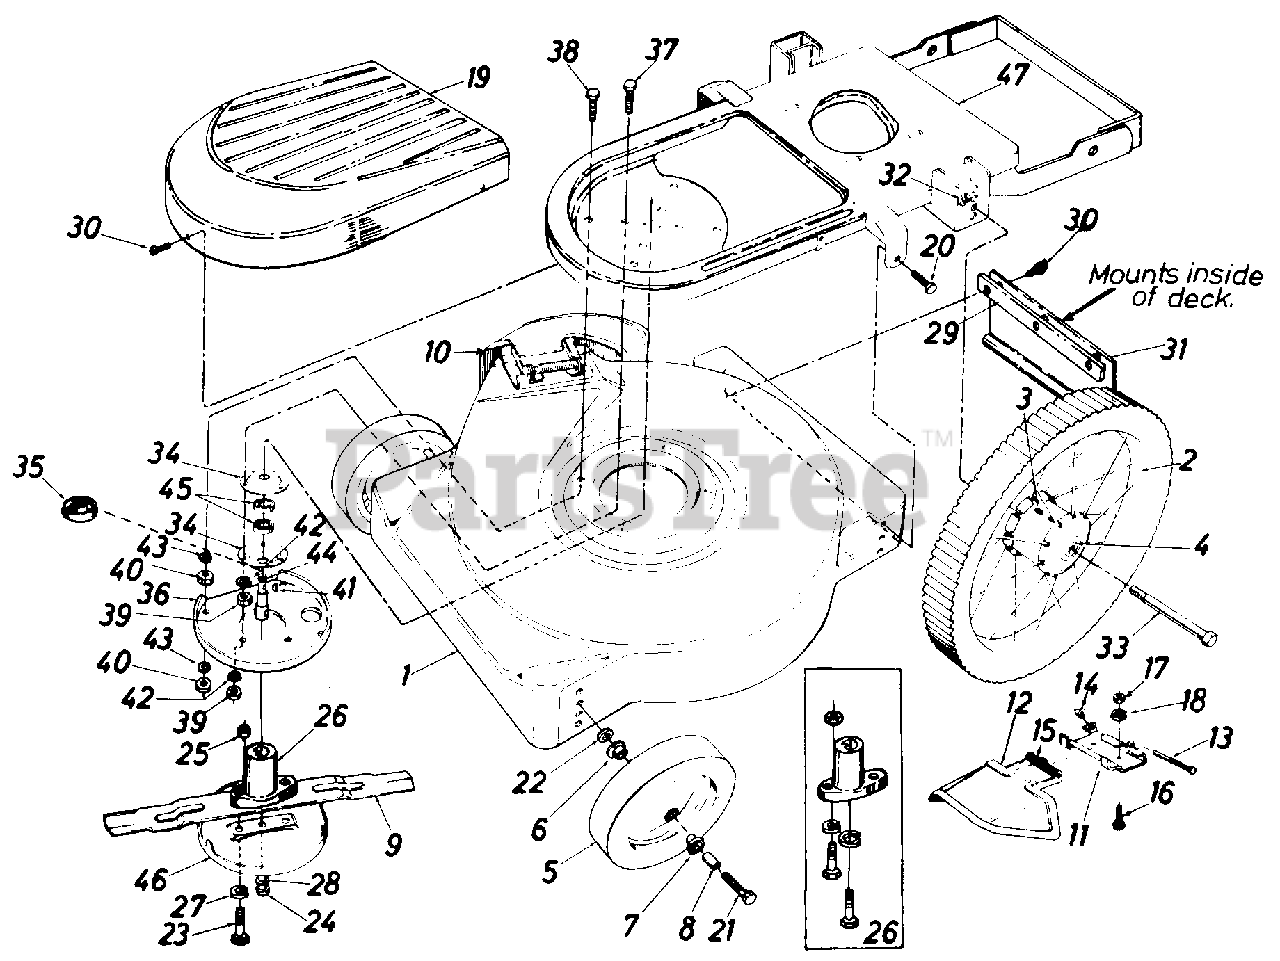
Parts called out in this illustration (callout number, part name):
3	Oil Cap
4	Ball Bearing
5	Wheel Ass'y. Comp. 8 x 1.75 (Twinline Tread)
6	Flanged Ball Bearing 3/8" I.D.
7	Flanged Ball Bearing 1/2" I.D
8	Spacer
9	22" Blade
10	Chute Deflector Ass'y. Comp.
11	Adapter Plate
12	Deflector Ass'y.
13	Pivot Pin
14	Push Cap 1/4n Rod
15	Torsion Spring
16	Hex Bolt 1/4-20 x .50" Lg.
17	Hex Nut 1/4-20 Thd.*
18	L-Wash. 1/4" I.D.
19	Blade Spindle Cover
20	Hex Sems Scr. 3/8-16 x .62"
21	Hex Bolt 3/8-16 x 2.0" Lg.
22	Bell-Wash. .400" I.D. x .88"
23	Hex Bolt 5/16-24 x 1.00" Lg.
24	Hex Bolt 3/8-24 x 2.25" Lg.
25	Hex Nut 5/16-24 Thd.
26	Blade Adapter Kit
27	L-Wash. 5/16" I.D.
28	L-Wash. 3/8" I.D.-H.D.
29	Retaining Strip
30	Hex Wash. Hd. AB-Tap Scr. 1/4" x .62" Lg*
31	Rear Flap Ass'y.
32	Bell-Wash. .400" I.D. x .88"
33	RearAxle Bolt
34	Bearing Housing
35	Bearing Shield
36	Blade Reinforcement Plate
37	Hex Bolt 5/16-24 x 1.25" Lg.
38	Hex Bolt 3/8-24 x 1.25" Lg.
39	Hex Nut 5/16-2 Thd.
40	Hex Nut 3/8-24 Thd.
41	#6 Hi-Pro Key 5/32" x 5/8" Dia.
42	L-Wash. 5/16" I.D.
43	L-Wash. 3/8" I.D.
44	Blade Spindle
